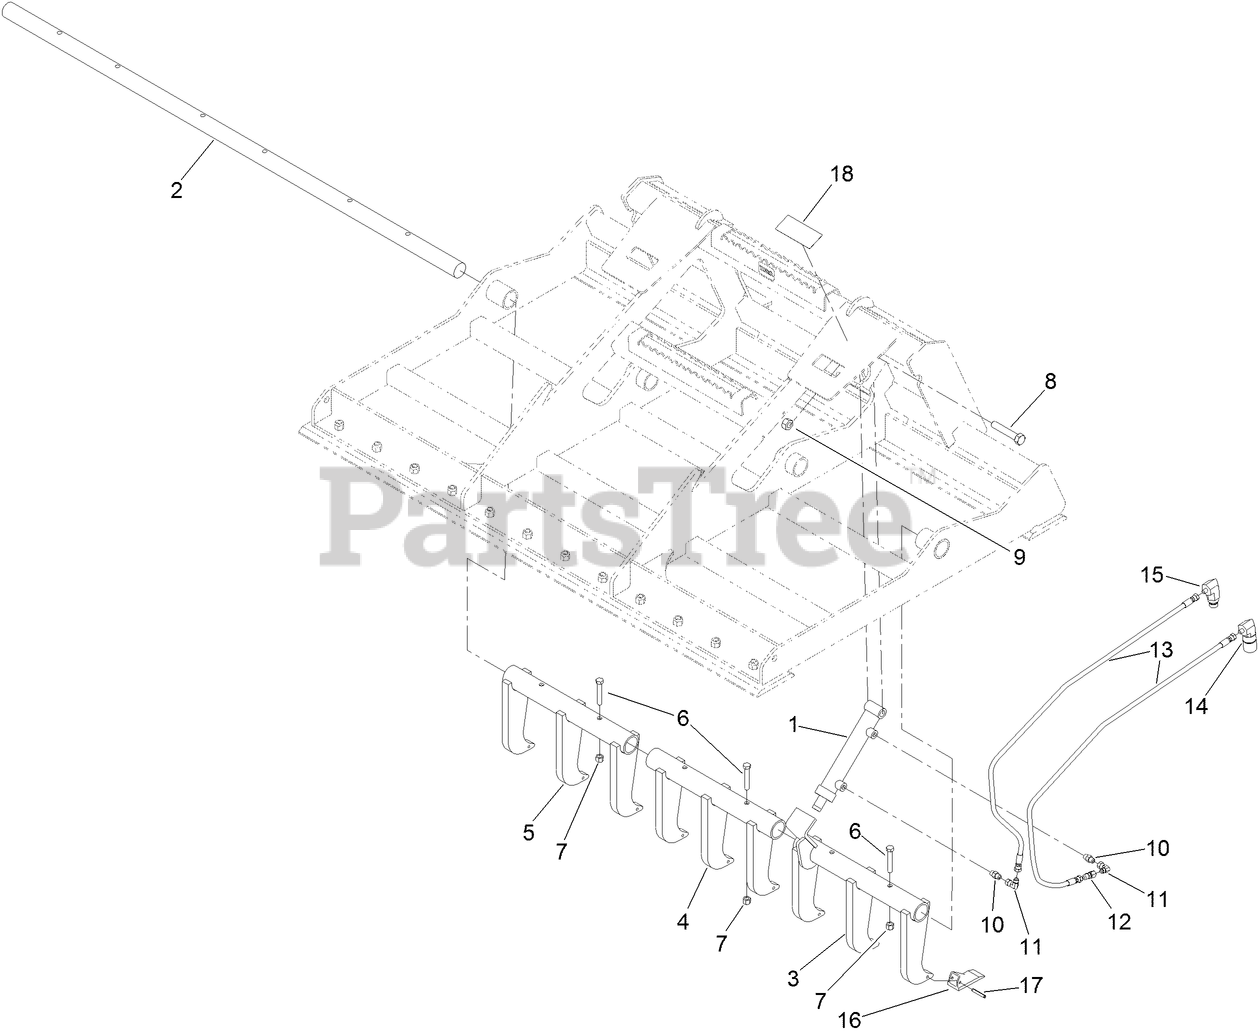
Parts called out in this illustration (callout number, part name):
1	HYDRAULIC CYLINDER ASM
2	SHAFT-SCARIFER
3	CLAW-SCARIFER
4	CLAW-SCARIFER
5	CLAW-SCARIFER
6	SCREW-HH
7	NUT-LOCK, NI
8	SCREW-HH
9	NUT-LOCK
10	FITTING-ADAPTER
11	ELBOW-SWIVEL, 90 DEG
12	FITTING-HYD
13	HOSE-HYD
14	FITTING-ELBOW
15	FITTING-ELBOW
16	TOOTH-SCARIFIER
17	PIN-SPRING
18	DECAL-WARNING
